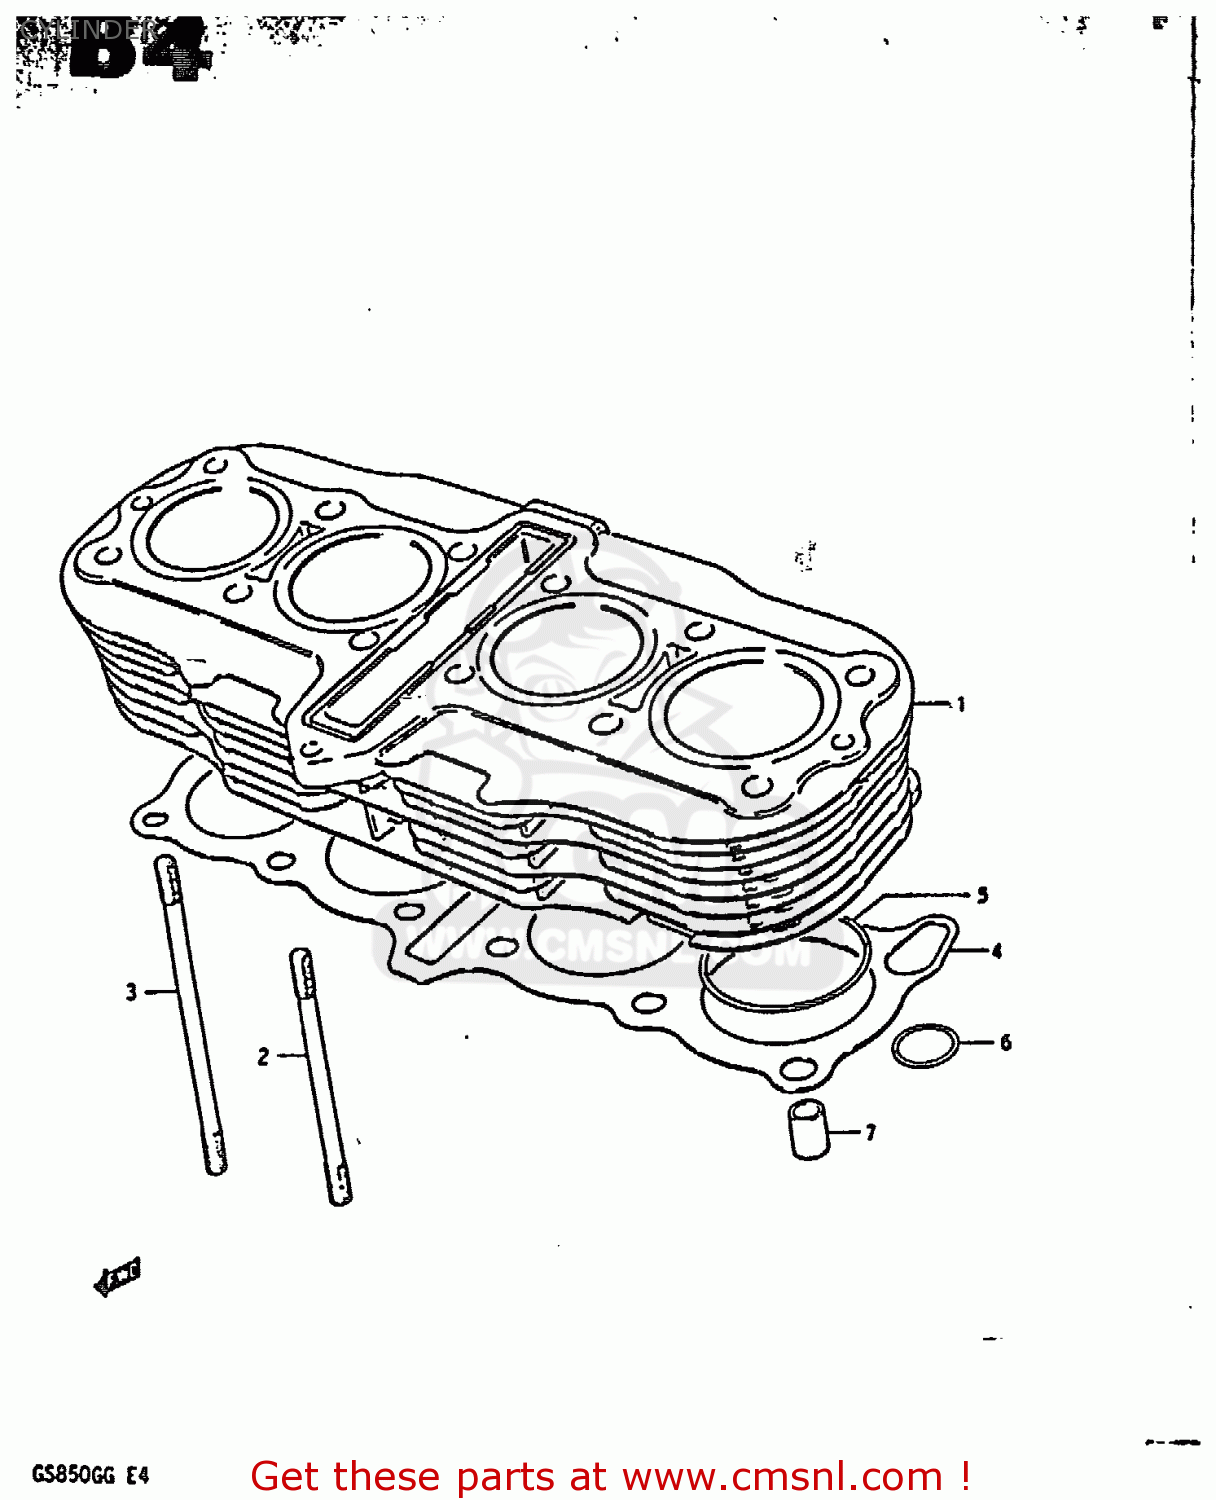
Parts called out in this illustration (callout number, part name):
1	CYLINDER
2	BOLT,STUD
3	STUD
4	GASKET,CYLINDER (MCA)
5	O RING(D:2,ID:70)
6	O RING(D:3.05)
7	PIN
